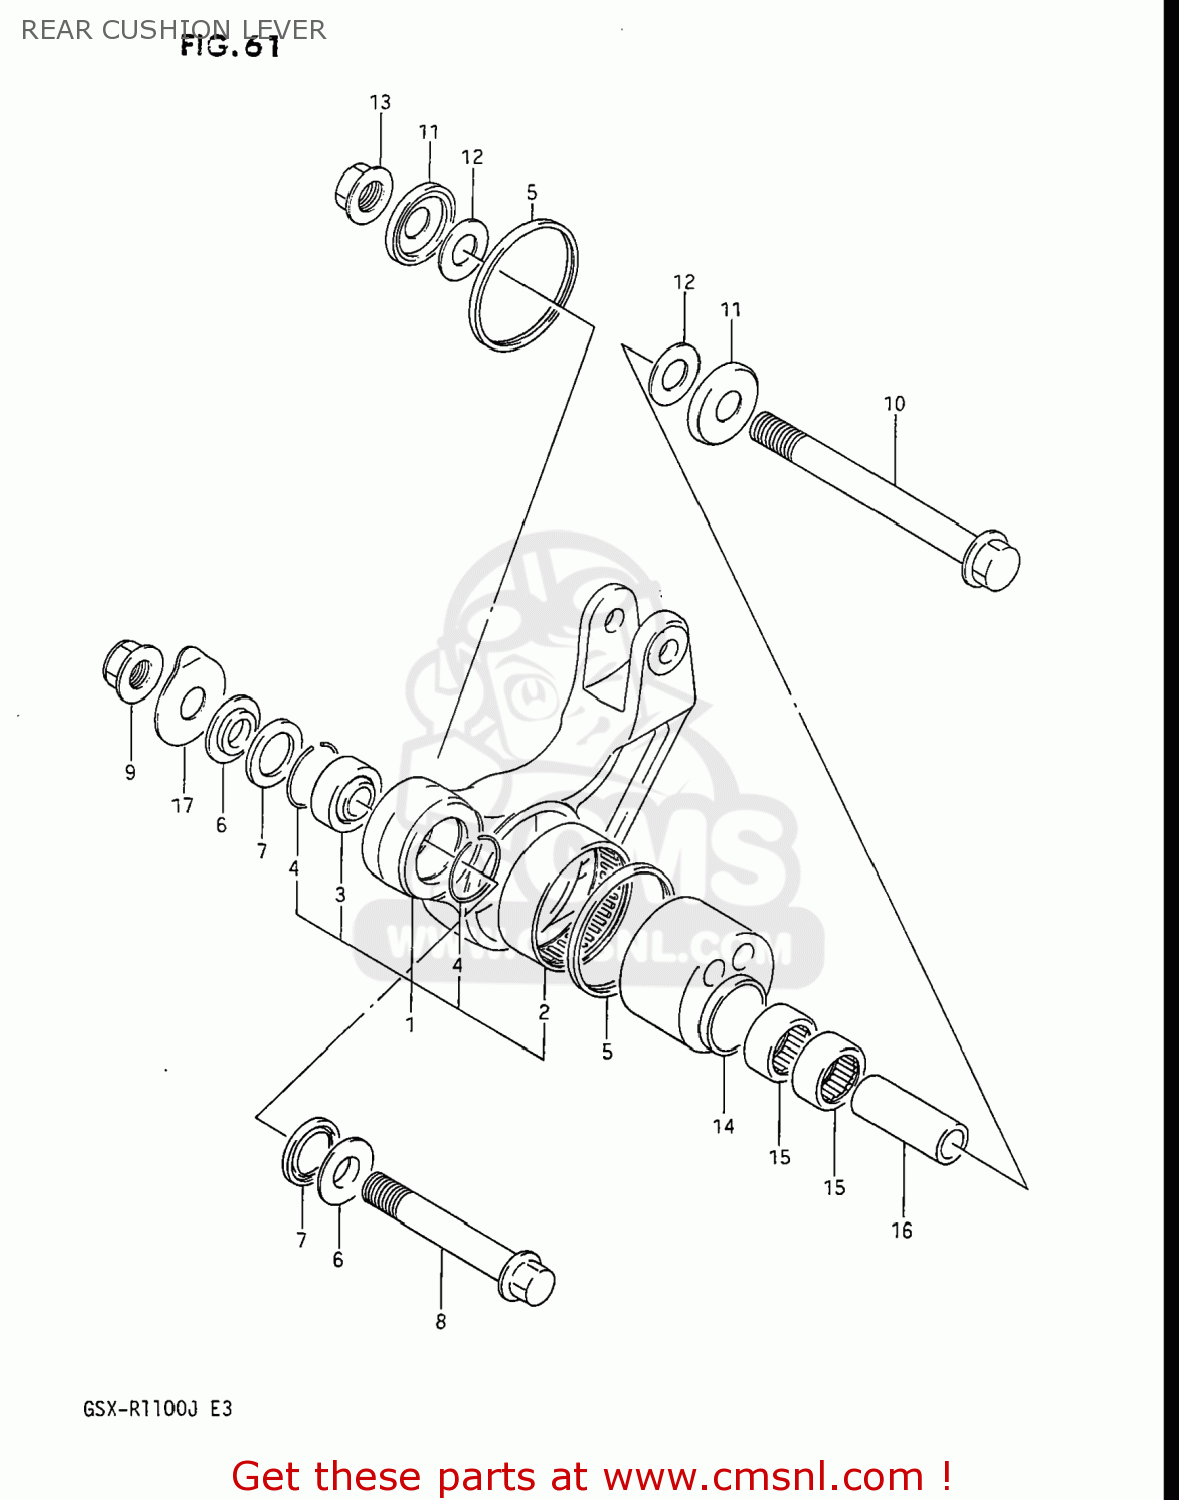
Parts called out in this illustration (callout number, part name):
1	LEVER SET,REAR CUSHION
2	BEARING(45X52X20)
3	BEARING(12X26X16)
4	RING,STOPPER
5	SEAL,ECCENTRIC LVR DUST CTR
6	SPACER,RR CUSHION ROD
7	SEAL,RR CUSHION ROD DUST
8	BOLT,RR CUSHION LEVER FR
9	NUT 12MM
10	BOLT(12X105)
11	COVER,REAR SWING ARM DUST
12	WASHER
13	NUT 12MM
14	ECCENTRIC SPACER,REAR SUSPENSION
15	BEARING(17X24X15)
16	SPACER,ECCENTRIC LVR CTR
17	SHIM,REAR CUSHION LEVER
